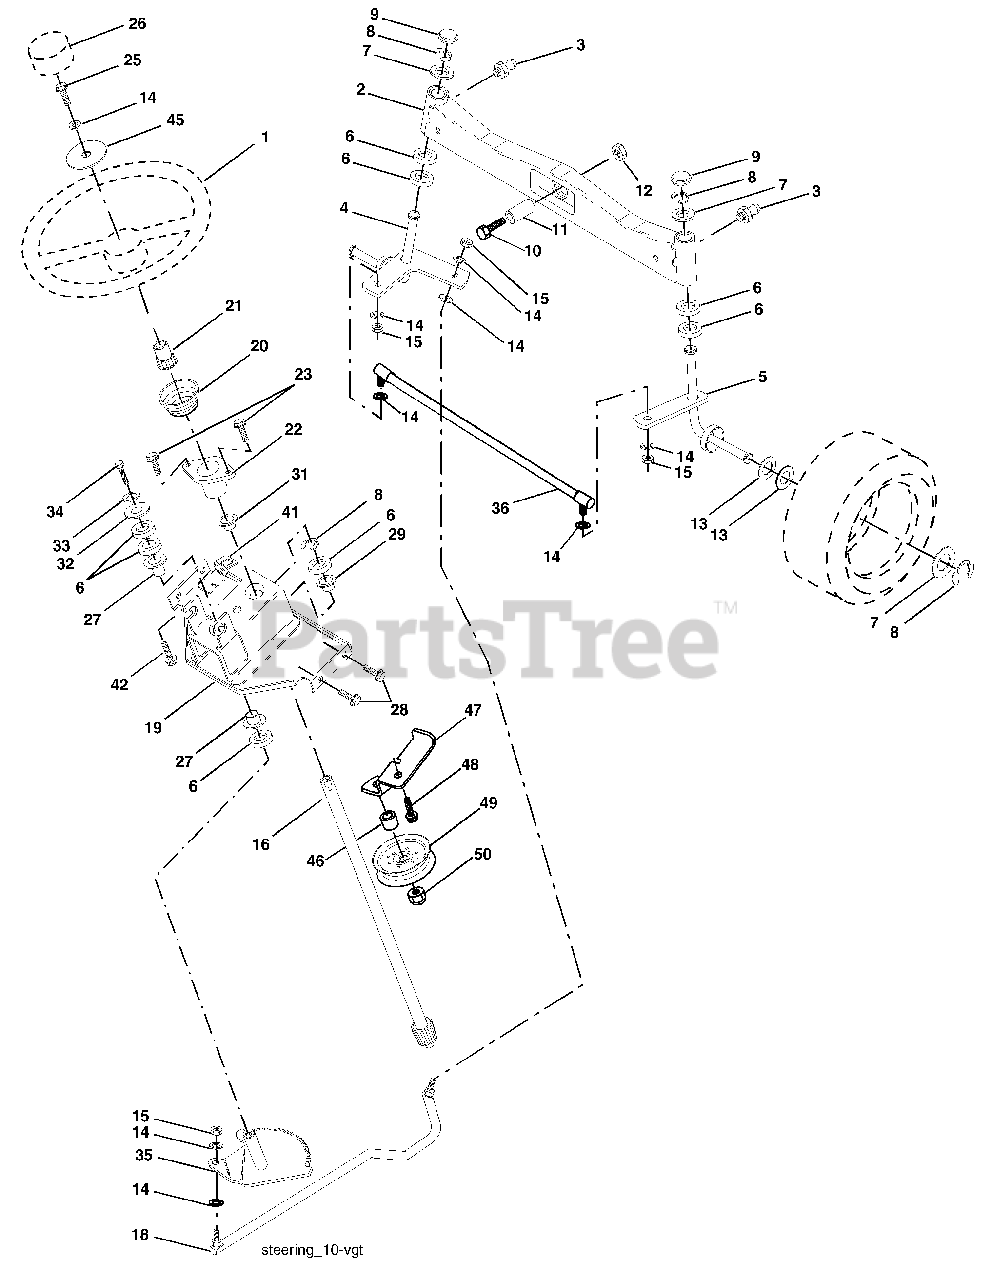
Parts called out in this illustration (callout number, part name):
1	Wheel, Steering
2	Axle Asm., Front
3	Fitting, Grease
4	Spindle Asm, LH
5	Spindle Asm., RH
6	Bearing, Race Thrust Harden
7	Washer 25/32 x 1-5/8 x 16 Ga.
8	Ring, Klip #T5304-75
9	Cap, Spindle
10	Bolt, Fin Hex 5/8-11 x 2-3/4
11	Spacer, Brg. Axle Front
12	Nut, Lock Flange 5/8-11 Unc
13	Washer 25/32 x 1-1/4 x 16 Ga.
14	Washer, Lock Hvy Hlcl Spr 3/8
15	Nut Lock Center 3/8-24 Unf
16	Shaft Asm., Steering
18	Draglink, Ball Joint Solid Vgt
19	Support Asm., Steering Vgt
20	Boot Steering Stealth
21	Adapter, Wheel Steering
22	Bushing, Strg.
23	Screw
25	Bolt, Fin Hex 3/8-16 x 1 Gr. 5
26	Insert Cap Strg WH
27	Bearing, Col. Strg.
28	Screw Hexwsh thdr 3/8-16 x 3/4
29	Bearing, Flange
31	Bushing, Nyliner Snap
32	Washer 11/32 x 1 x 10 Ga.
33	Washer, Lock Hvy Hlcl Spr 5/16
34	Bolt, Hex Hd 5/16-18 x 3/4
35	Gear, Sector Steering
36	Tie Rod
41	Bracket Switch Interlock Vgt 97
42	Screw Thdrol 5/16-18 x 1/2 Tyt
45	Washer 13/32 x 1-1/2 x 11 Ga.
46	Washer 13/32 x 1 x 10 Ga.
47	Bracket Asm. Idler Stationary
48	Screw 3/8-16 x .75
49	Pulley Idler Flat
50	Nut Lock Flg. 3/8-16 Unc
